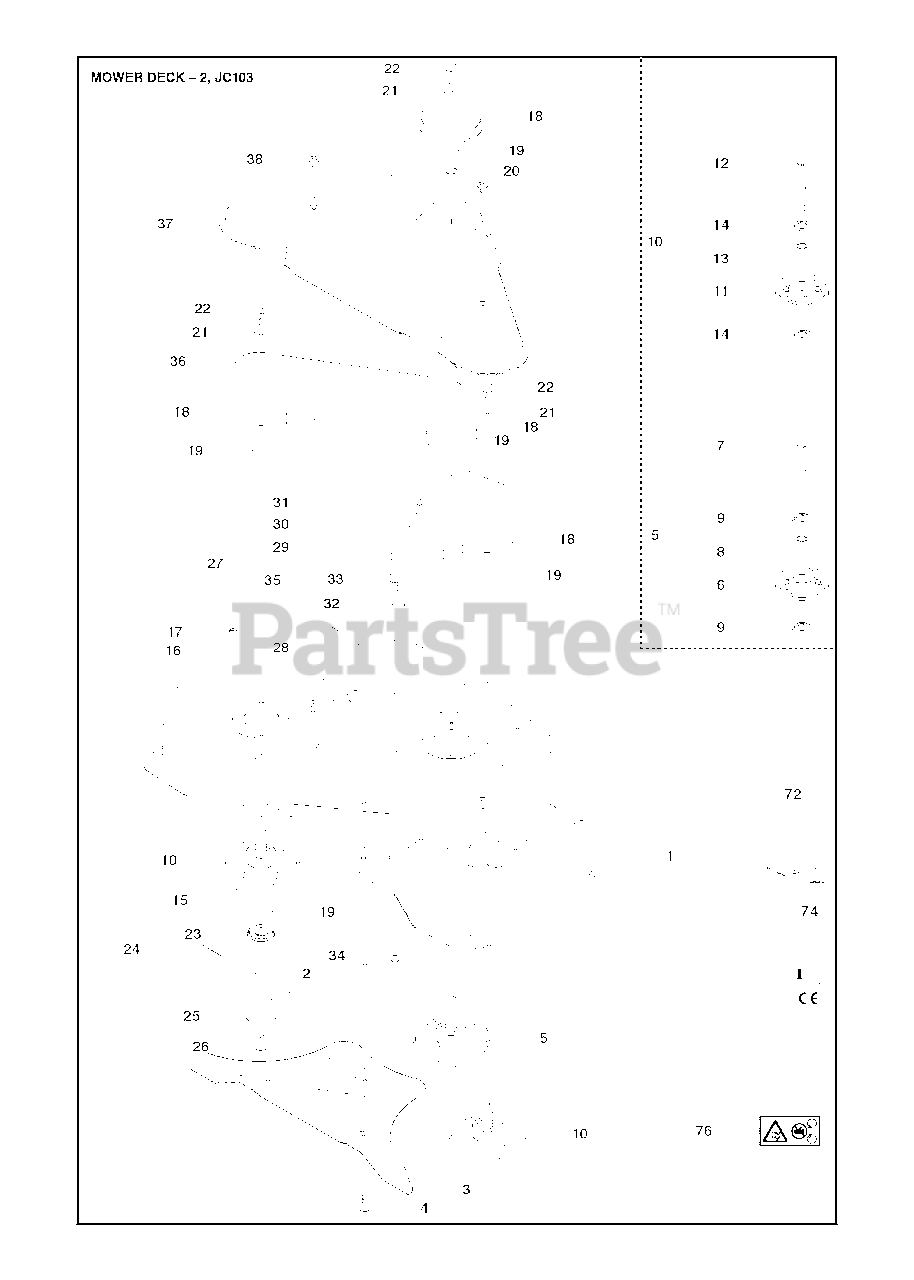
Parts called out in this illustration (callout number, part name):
5	BLADE HOUSING ASSY
6	BEARING HOUSING
7	SHAFT
8	SPACING SLEEVE
9	BEARING
10	BLADE HOUSING ASSY
11	BEARING HOUSING
12	SHAFT
13	SPACING SLEEVE
14	BEARING
16	WASHER BRB 8.4X17
17	LOCKNUT M8
24	BLADE
27	BELT TENSIONER ASSY
28	BELT TENSIONING ARM
29	PULLEY
30	SPACER
31	BOLT
32	WASHER
34	LOCKNUT M8
36	BELT
